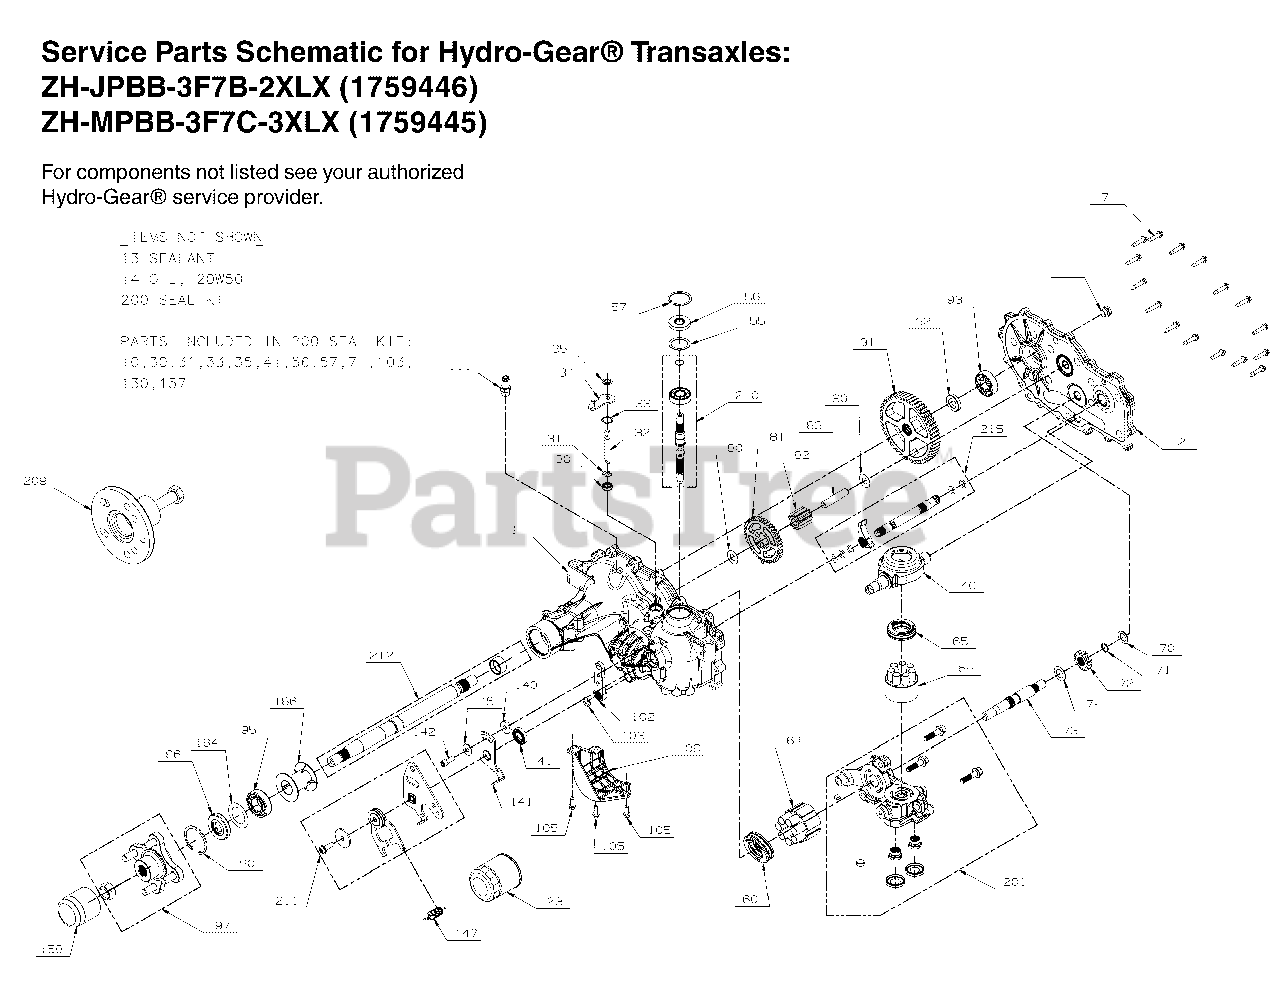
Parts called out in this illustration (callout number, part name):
23	FILTER, OIL,
56	SEAL, Lip, .67 x 1.58 x .276
57	RING, RET 2.06 INT,
90	RING, RETAINING 2.25 INTERNAL (50859)
93	KIT, BEARING (72749)
96	SEAL, LIP, AXLE,#53699
97	KIT, Hub Replacement
103	E-CLIP, Brake Arm
147	SPRING, Extension (52401)
186	DEBRIS GUARD HG #53496
